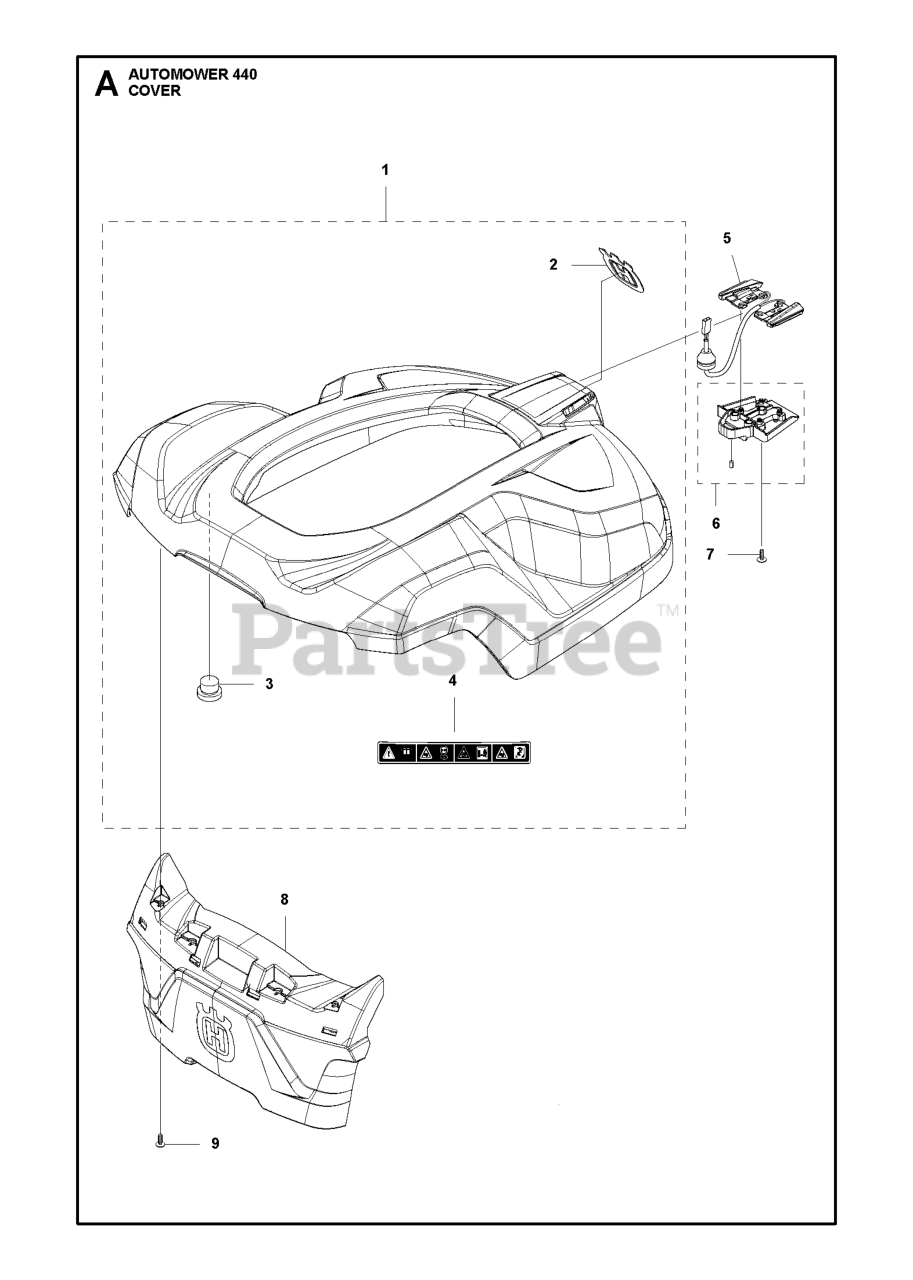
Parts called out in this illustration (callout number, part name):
2	DECAL HUSQVARNA CROWN HEIGHT 5
3	CAP SNAPLOC
4	LABEL WARNING P15
5	CABLE ASSY CHARGING PLATE
6	HOLDER ASSY MAGNET
7	SCREW 14MM
8	BUMPER REAR
9	SCREW ITXPANT
